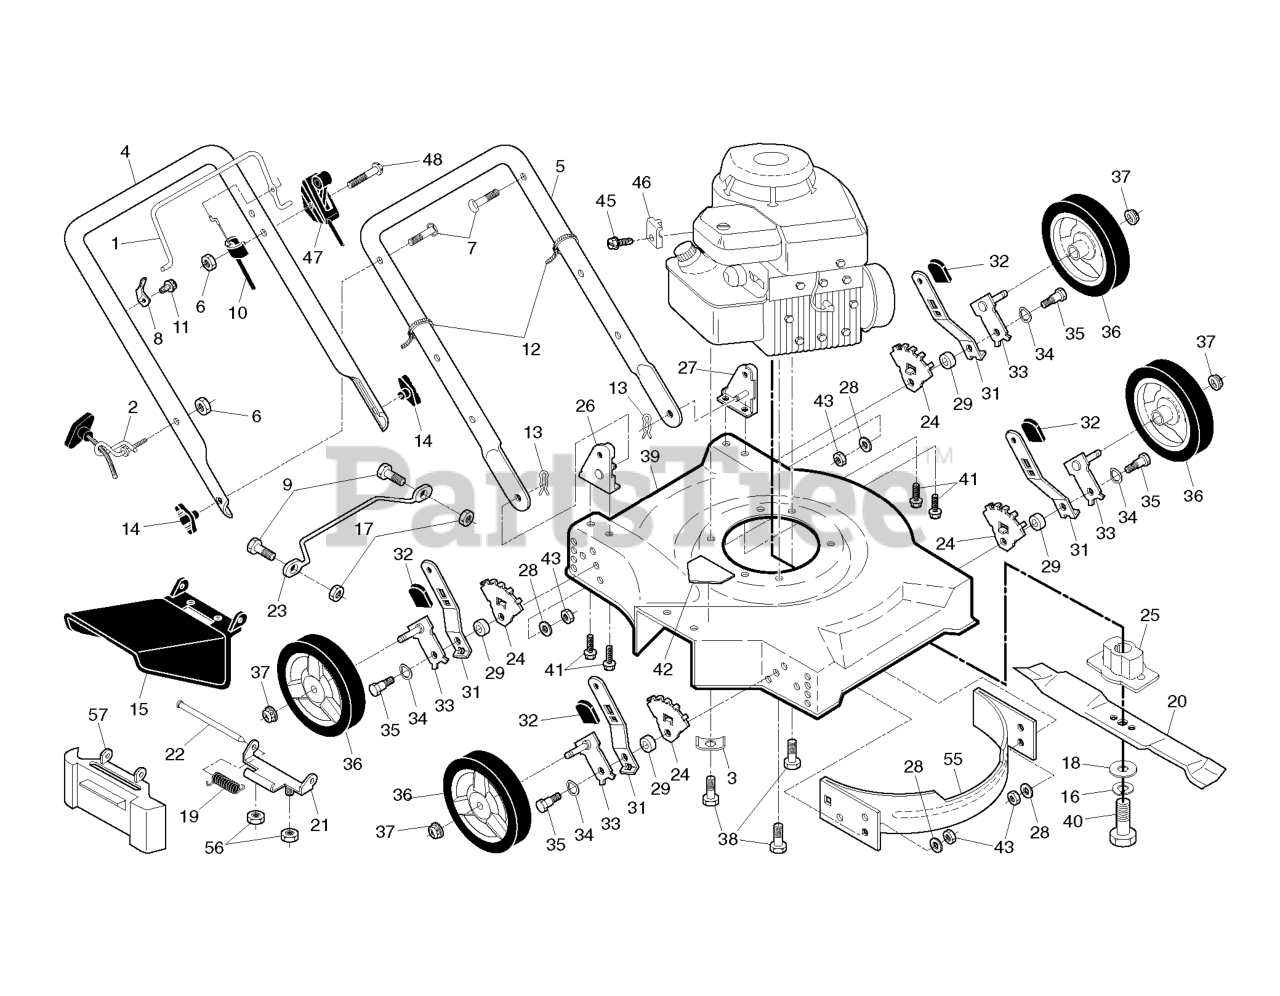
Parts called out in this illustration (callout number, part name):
1	CARBURETOR
4	METERING DIAPHRAGM
5	GASKET METERING SIDE
9	PIN RETAINING SCREW
11	INLET NEEDLE
12	SPRING
16	CHOKE SHAFT
19	DISC
26	PUMP DIAPHRAGM
32	THROTTLE SHAFT
33	THROTTLE FLAP
36	LIMITER CAP
37	LIMITER CAP
38	NEEDLE HIGH SPEED
39	NEEDLE LOW SPEED
40	WASHER
41	SLEEVE
42	SLEEVE
43	SCREW
44	IDLE SCREW
45	SPRING
46	GASKET SET
